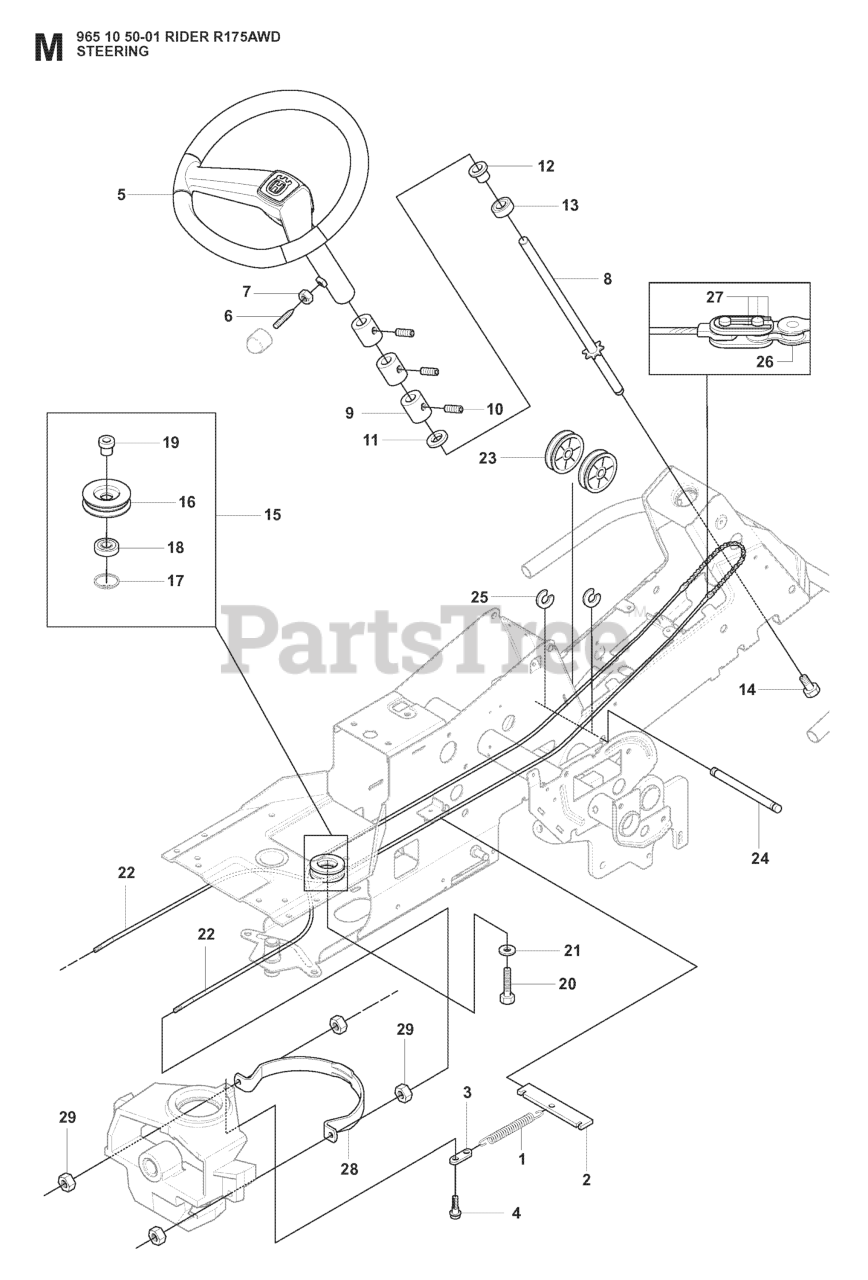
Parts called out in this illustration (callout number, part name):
2	SPRING BRACKET
5	STEERING WHEEL
7	NUT
8	ROD STEERING ASSY
9	SPACER
13	BALL BEARING 6004-2RS1
17	CIRCLIP SGH 47
18	BALL-BEARING 6204-2RS
22	RP STEERING CABLE COMPLETE
25	RETAINING RING
26	STEERING CHAIN
28	WIRE GUIDE
29	NUT
